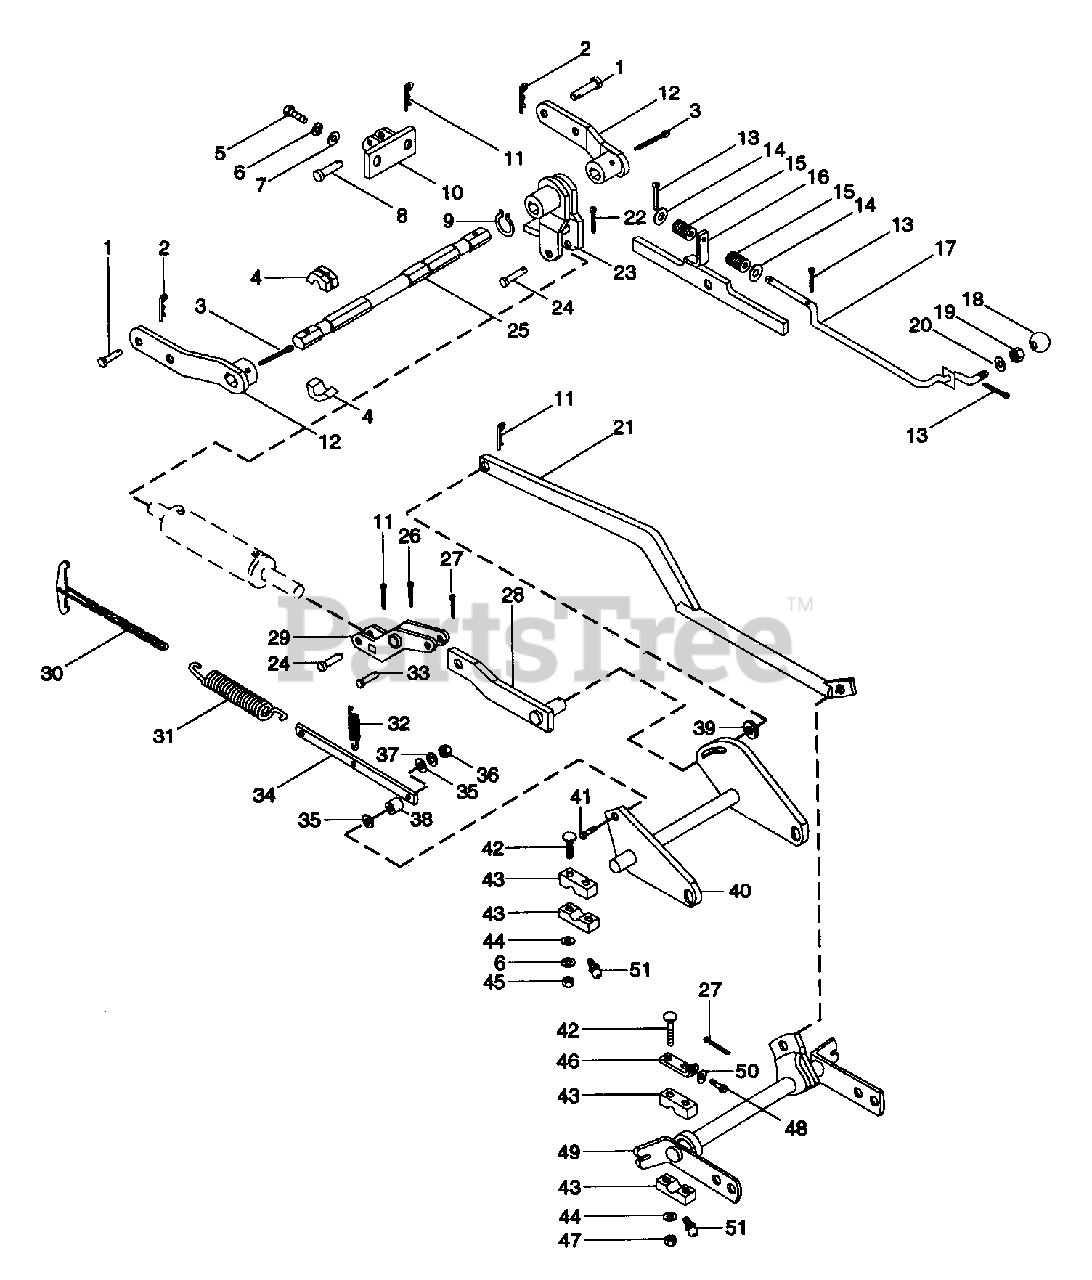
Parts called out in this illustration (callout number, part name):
1	PIN-CLEV .50X1.25 RH ST PL
2	PIN-HAIR INT .14X.4X2.75
3	PIN-COTR .18X2.0 ZCC
4	BSHG-FLG 1.000X1.750X1.000
5	BLT-HEX .38-16X1.00 PL
6	WSHR-LK .375X.094 MED PL
7	WSHR-FL-STL .438X1.0X.083 PL
8	PIN-CLEV .619X2.0 YWZC
9	RG-RTNG-EXT 1.125X.050
11	PIN-HAIR INT .09X.188 PL
13	PIN-COTR .12X.75 PL
14	WSHR-FL-STL.406X.812X.065PL
15	SG-COMP .65X.56X1.50
17	LATCH ROD
18	KNOB-STEERING LOCK
19	NUT-JAM .375-16 PL
20	WSHR-FL-STL .406X1.00X.062 PL
21	CONNECTOR LINK
22	PIN-COTR .12X1.0 PL
24	PIN-CLEV .494X1.94 YWZC
26	PIN-COTR .18X1.25 PL
27	PIN-COTR .18X1.0 PL
29	BELLCRANK
31	SG-TENS .156X1.062X8.68 WLD ??
32	SG-TENS .035X.45X2.75 WLD 3.5
33	PIN-CLEV .619X1.43 YWZC
35	WSHR-FL-STL.281X.62X.065 PL
36	NUT-HEX .250-20 PL
37	WSHR-LK .250X.077 HVY PL
38	SPACER .269X.375X.343
39	WSHR-FL-STL.812X1.500X.139
40	CENTER ROCKSHAFT
41	BLT-HEX .25-20X1.00 GR2
42	BLT-RDHDSQNK .38-16X2.25 SHTPL
44	WSHR-FL-STL .406X.750X.005
45	NUT-HEX .375-16
47	NUT-LK-CTR .375-16 GR A PL
48	BLT-HEX .31-18X1.25 PL GR5
49	ROCK SHAFT-FRONT
50	WSHR-LK .312X.097 PL HVY
51	SPIN DRIVE ZERK FITTING
